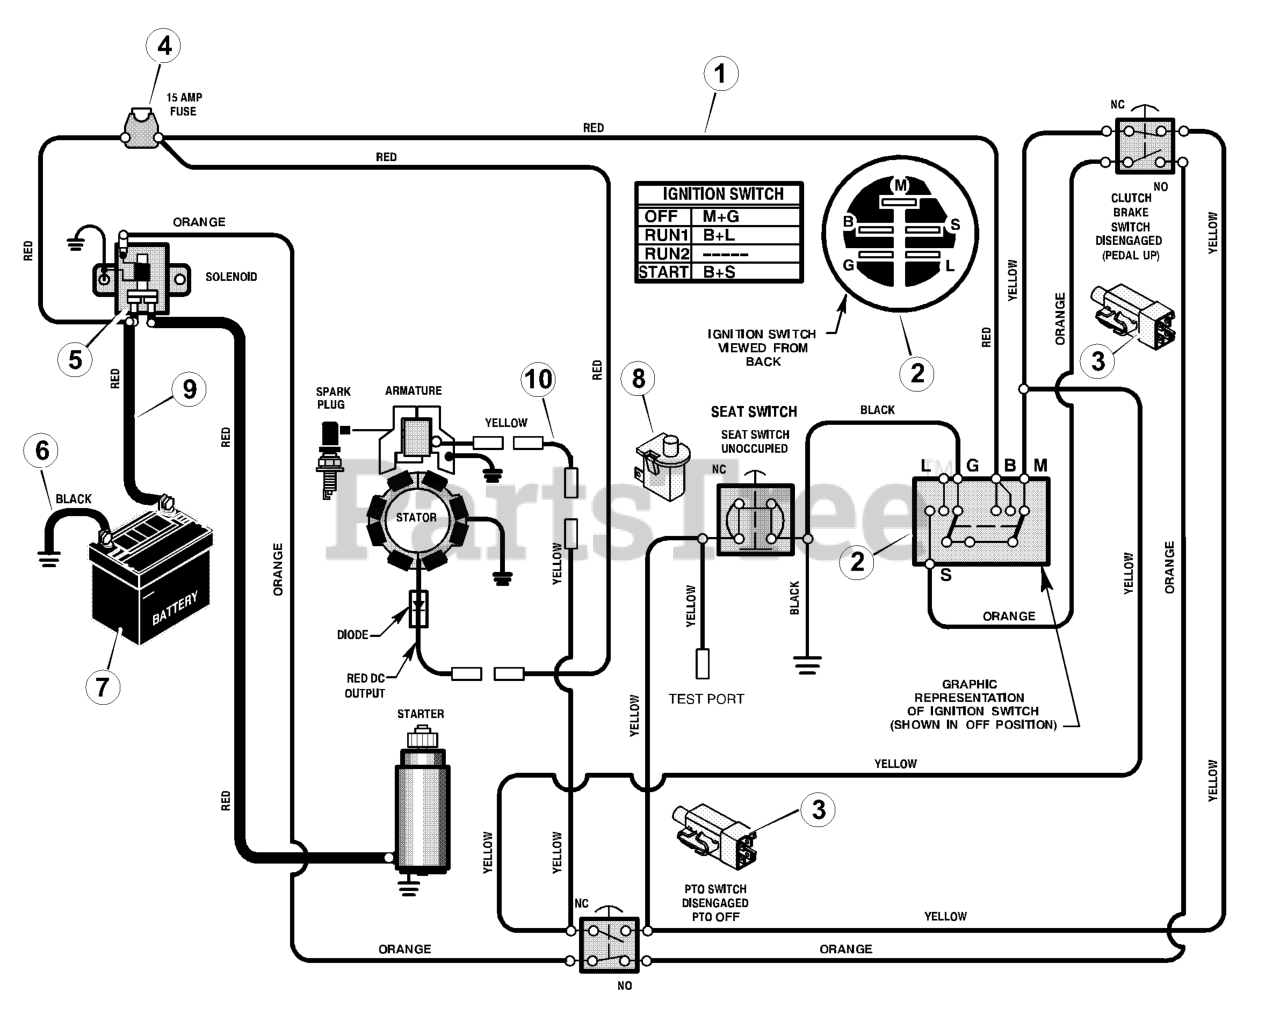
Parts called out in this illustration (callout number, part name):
1	Harness, Chassis Wire
2	Switch, Ignition
3	Switch, Limit
5	Solenoid
6	Cable, Battery Ground
7	Battery
8	Switch, Seat Sensor
9	Cable, Red Battery
10	Wire, Jumper
